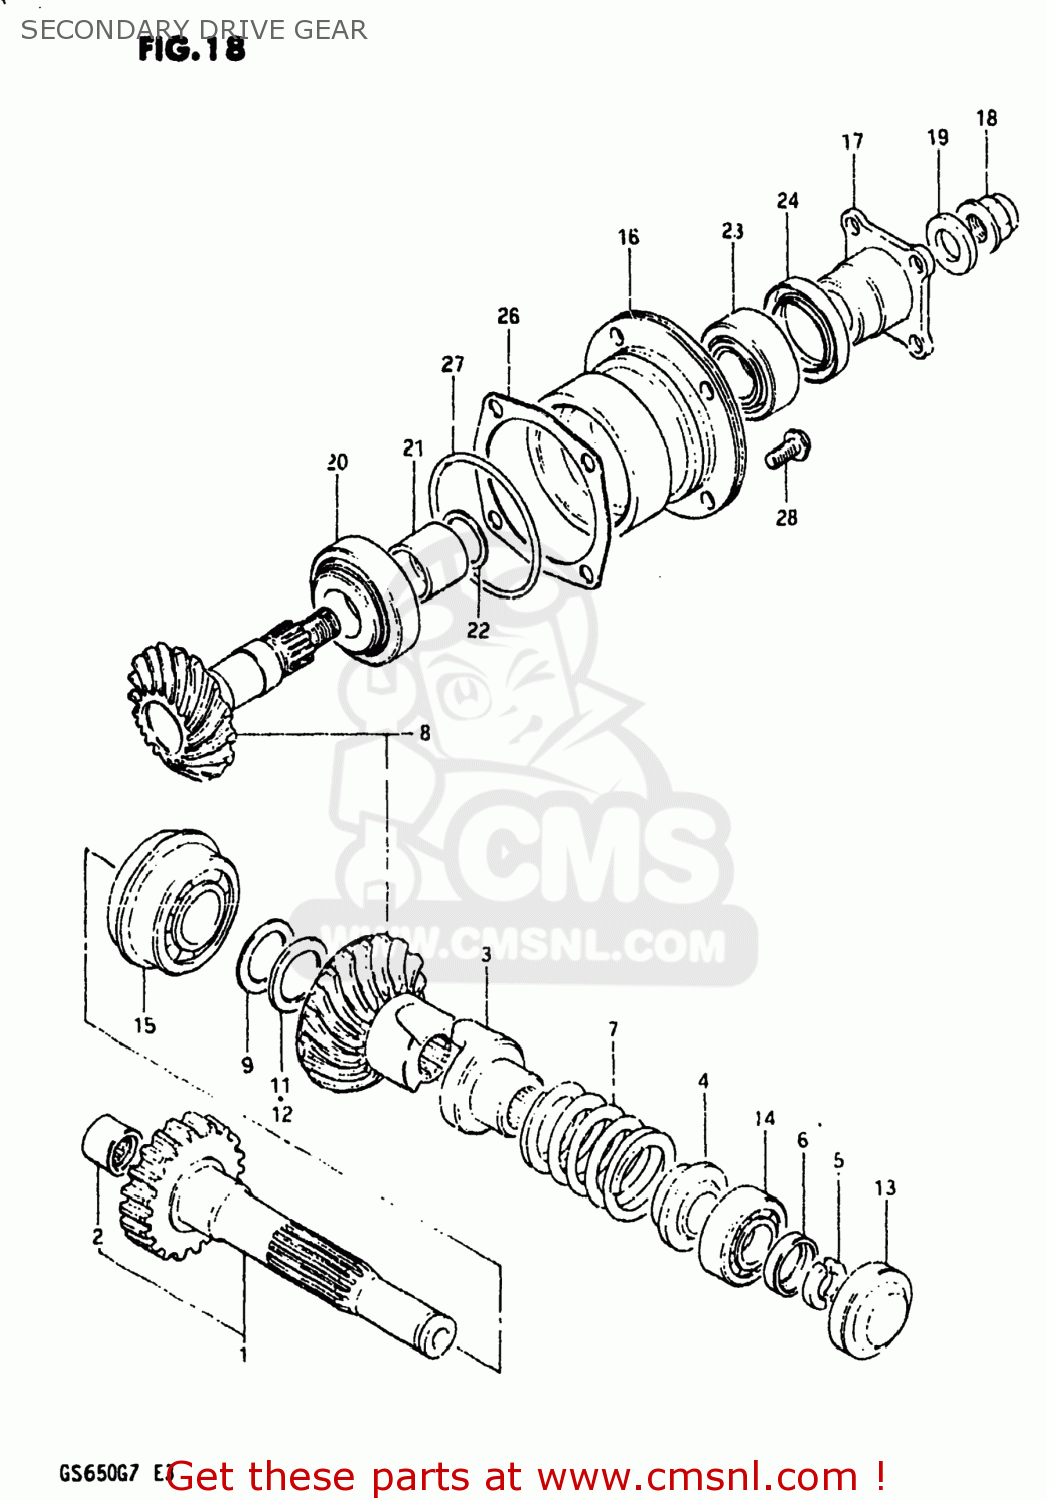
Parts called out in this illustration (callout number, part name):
1	SHAFT,OUTPUT
2	BEARING(15X23X20)
3	DOG
4	STOPPER
5	STOPPER,CAM DOG
6	HOLDER,CAM DOG STOPPER
7	SPRING
8	SECONDARY GEAR SET
9	SHIM,SECONDARY DRIVE
10	SHIM SET,SECONDARY DRIVE BEVEL
11	SHIM,SECONDARY DRIVE BEVEL
12	SHIM,SECONDARY DRIVE BEVEL
13	PLUG
14	BEARING(20X47X14)
15	BALL BEARING 30X62X24
16	HOUSING,SECONDARY DRIVE
17	FLANGE,UNIVERSAL JOINT
18	NUT
19	WASHER(14X29X4)
20	TAPER,ROLLER BEARING
21	SPACER (25.2X30X40)
22	SHIM (25X30X2
23	BEARING
24	SEAL,OIL(35X52X9)
25	SHIM SET,SECONDARY DRIVE
26	SHIM,DRIVEN GEAR HOUSING
27	O RING(D:3.1,ID:69.4)
28	BOLT
